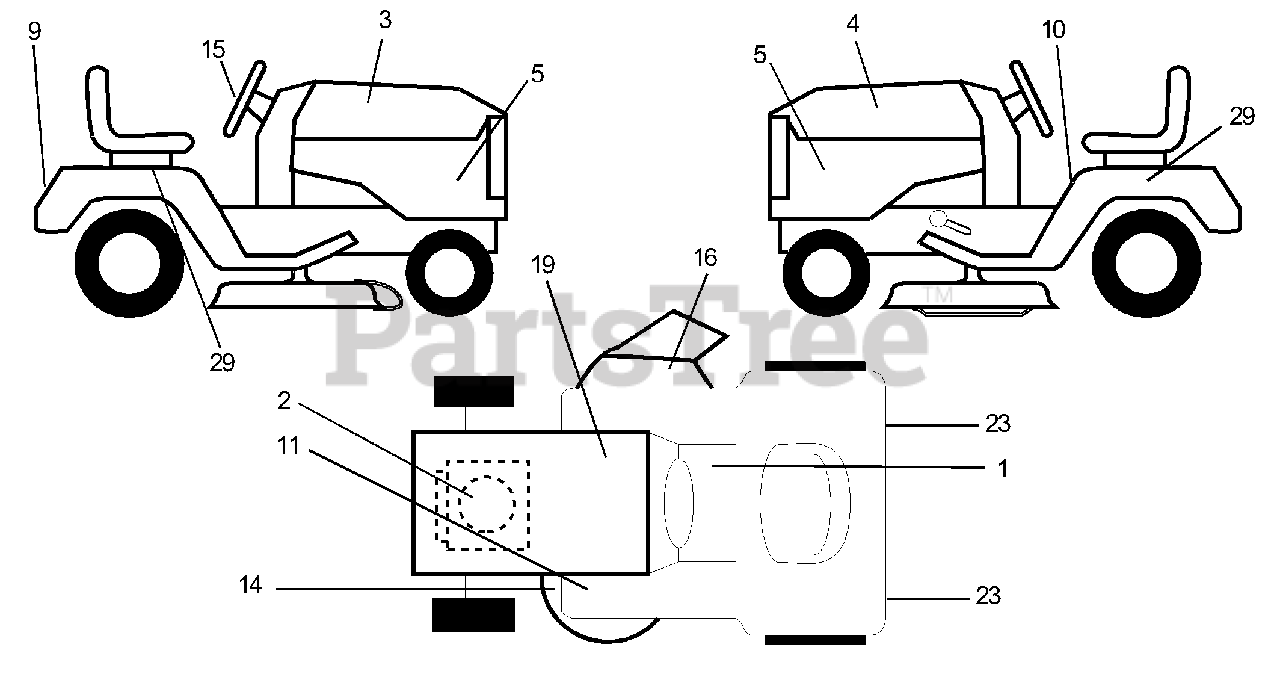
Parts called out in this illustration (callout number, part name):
1	Decal, Dash
2	Decal, Engine
3	Decal, Hood, RH
4	Decal, Hood, LH
5	Decal, Hood Side PNL
9	Decal, Fender
10	Decal, Danger
11	Decal, Clutch/Brake
14	Decal, V-Belt Schematic
15	Decal, Ins. Whl. Strg.
16	Decal, Housing Mower, Warning
19	Decal, Battery
23	Reflector, Taillight
29	Decal, Fender
